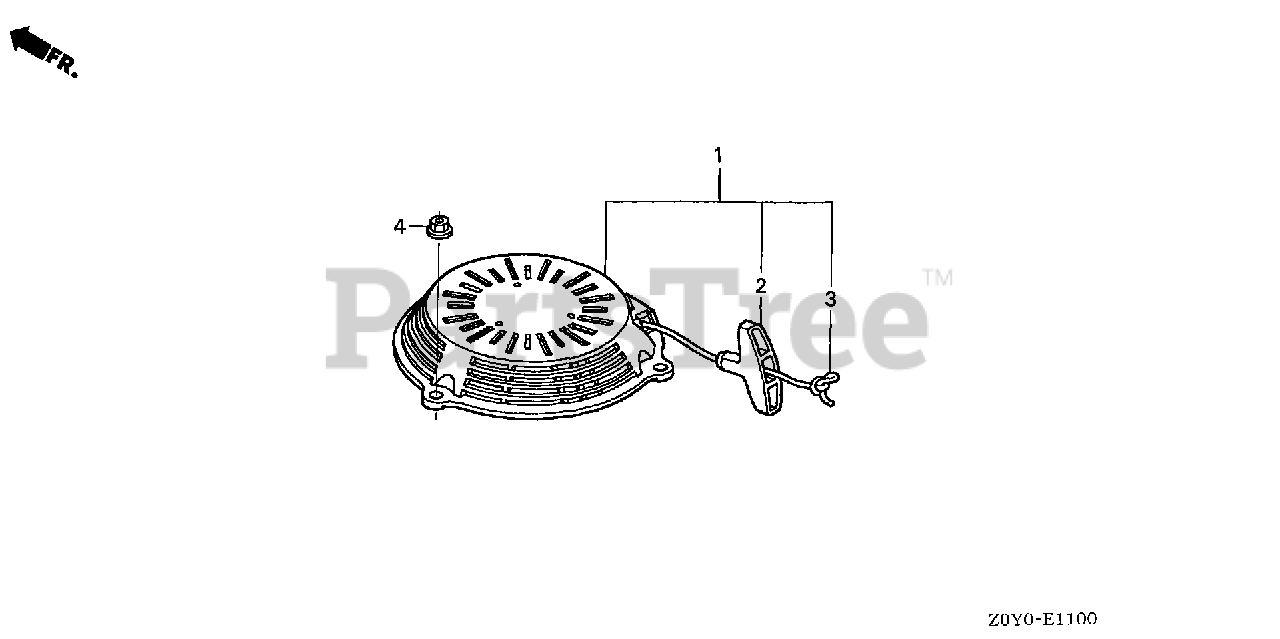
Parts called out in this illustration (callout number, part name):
1	STARTER ASSY., RECOIL *R280* (POWER RED)
1	STARTER ASSY., RECOIL *NH1* (BLACK)
2	KNOB, RECOIL STARTER
3	ROPE, RECOIL STARTER (Honda Code 5580642). (#3.5X90")
4	NUT, FLANGE (6MM)
